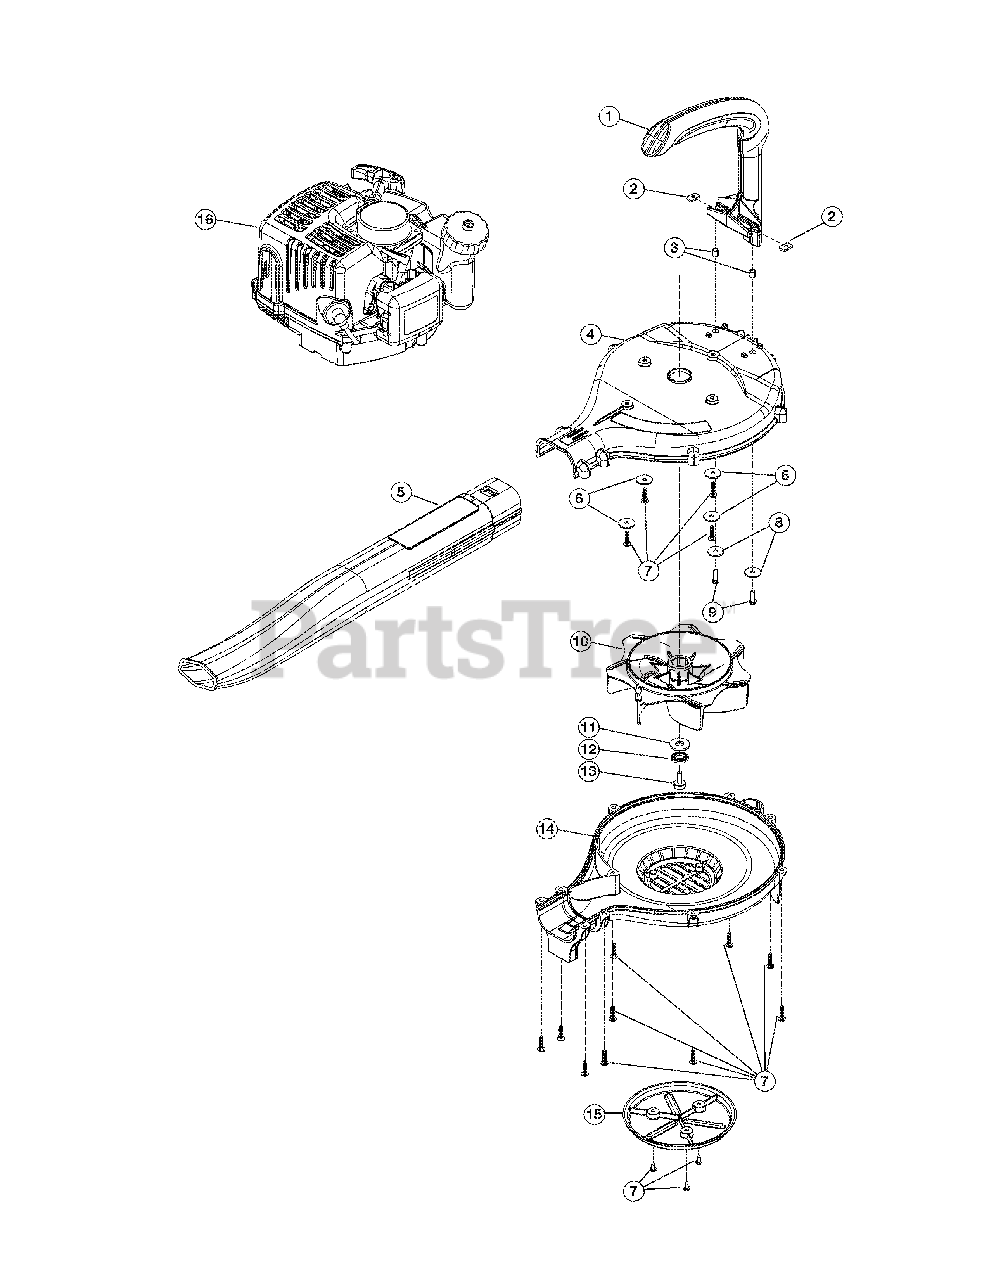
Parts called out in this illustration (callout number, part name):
1	Blower Handle
2	Weldnut
3	Spacer
4	Upper Impeller Housing
5	Blower Tube
7	Housing Screw
8	Handle Washer
9	Handle Screw
10	Impeller
11	Washer
12	Lock Washer
13	Bolt
14	Lower Impeller Housing
15	Intake Deflector
16	Engine Assembly
